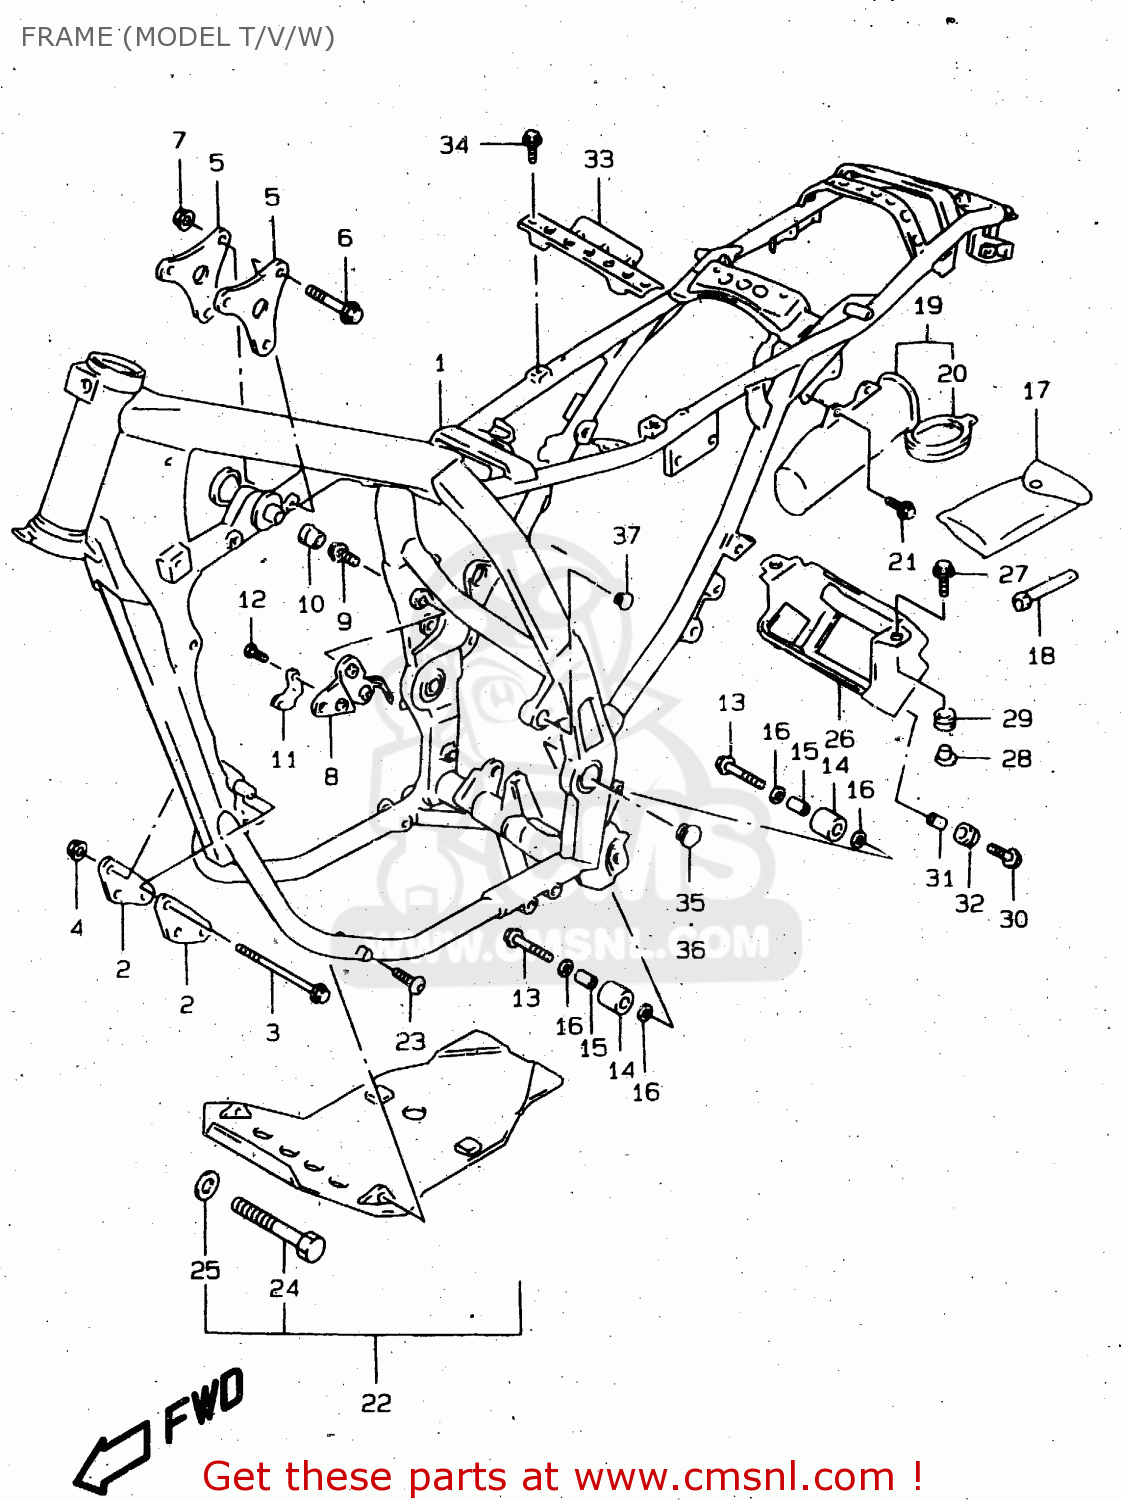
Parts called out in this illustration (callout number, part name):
1	FRAME COMP
2	PLATE,ENG MTG FR
3	BOLT(8X100)
4	NUT
5	PLATE,ENG MTG UPR
6	BOLT
7	NUT
8	PLATE,ENG MTG RR,R
9	BOLT
10	PLUG(OD:22)
11	BRACKET,STOP SWITCH
12	SCREW
13	BOLT(8X38)
14	ROLLER,CHAIN CONTROL UPR
15	SPACER(8.6X12X25.5)
16	WASHER
17	TOOL ASSY
18	SPARK PLUG WRENCH(16)
19	HOLDER,TOOL
20	CAP,HOLDER
21	BOLT(6X16)
22	Skid Plate
23	BOLT(8X14)
24	BOLT(10X245)
25	WASHER(10X24X2)
26	HOLDER,BATTERY
27	BOLT(6X20)
28	WASHER
29	CUSHION
30	BOLT(6X16)
31	SPACER(6.1X9X7.5)
32	CUSHION
33	PLATE,BATTERY FITING
34	BOLT
35	PLUG,FRAME PIVOR,R
36	PLUG,FRAME PIVOR,L
37	PLUG,FRAME BOSS
